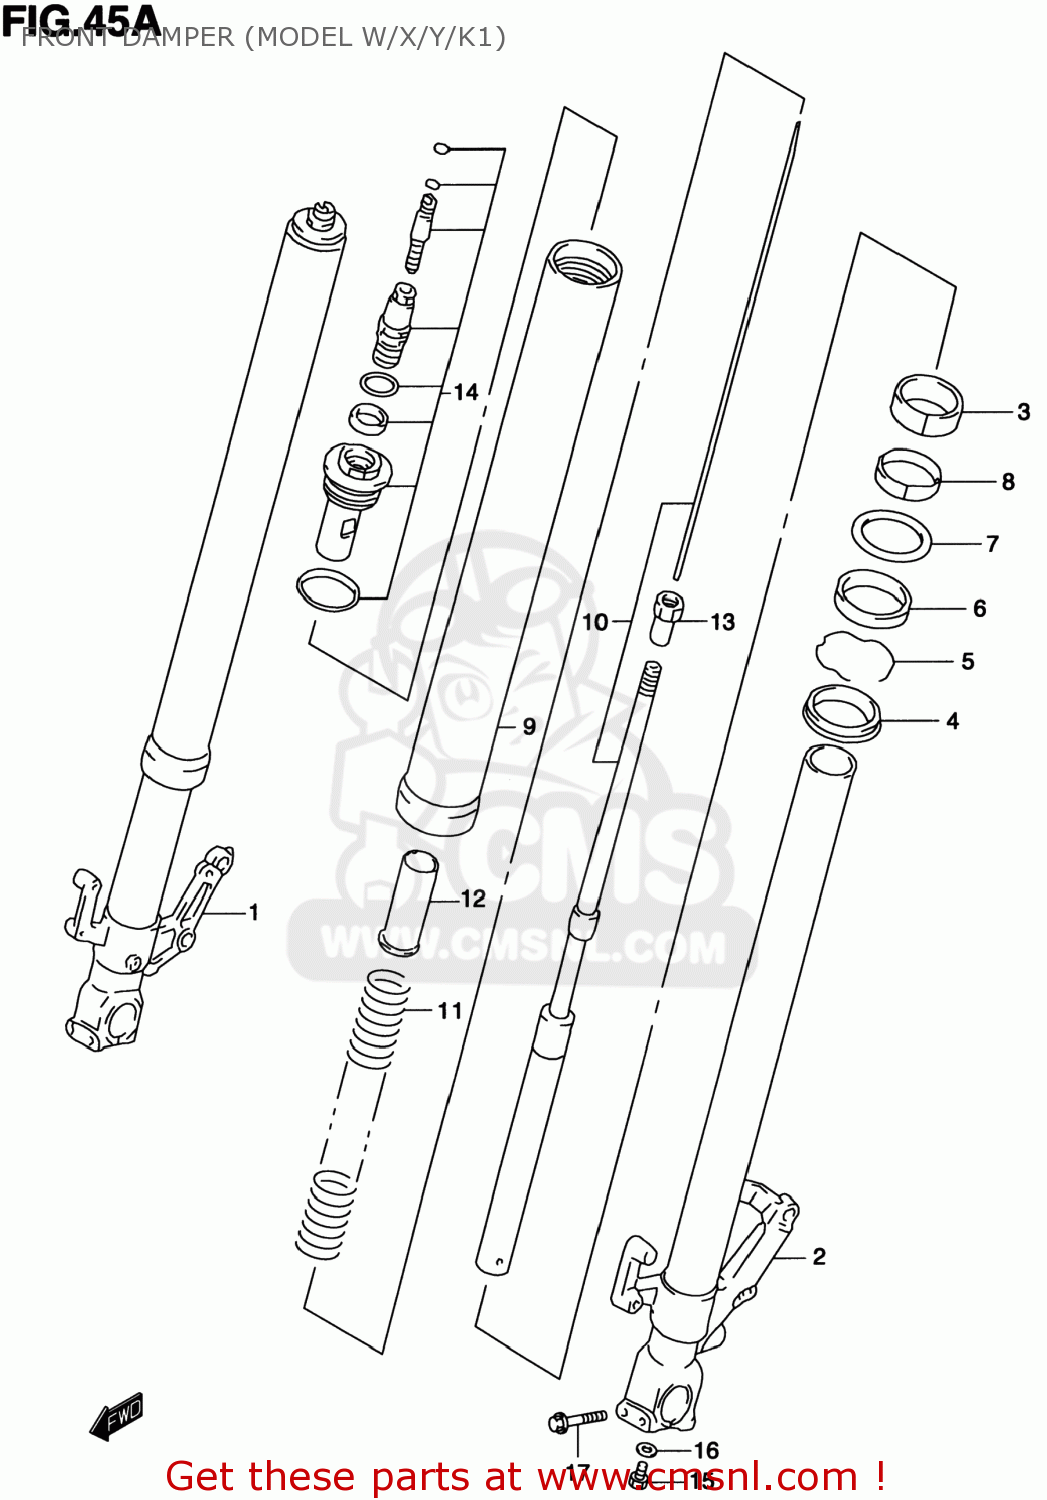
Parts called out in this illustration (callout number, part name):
1	TUBE,INNER,R
2	TUBE,INNER,L
3	PISTON
4	SEAL,DUST
5	RING,STOPPER
6	SEAL,OIL
7	WASHER
8	METAL,SLIDE
9	TUBE,OUTER
10	CYLINDER
11	SPRING,FR
12	SPACER
13	NUT,PISTON ROD
14	CAP,FORK
15	BOLT,OIL LOCK PIECE,12X22
16	GASKET,CYLINDER (NAS)
17	BOLT
